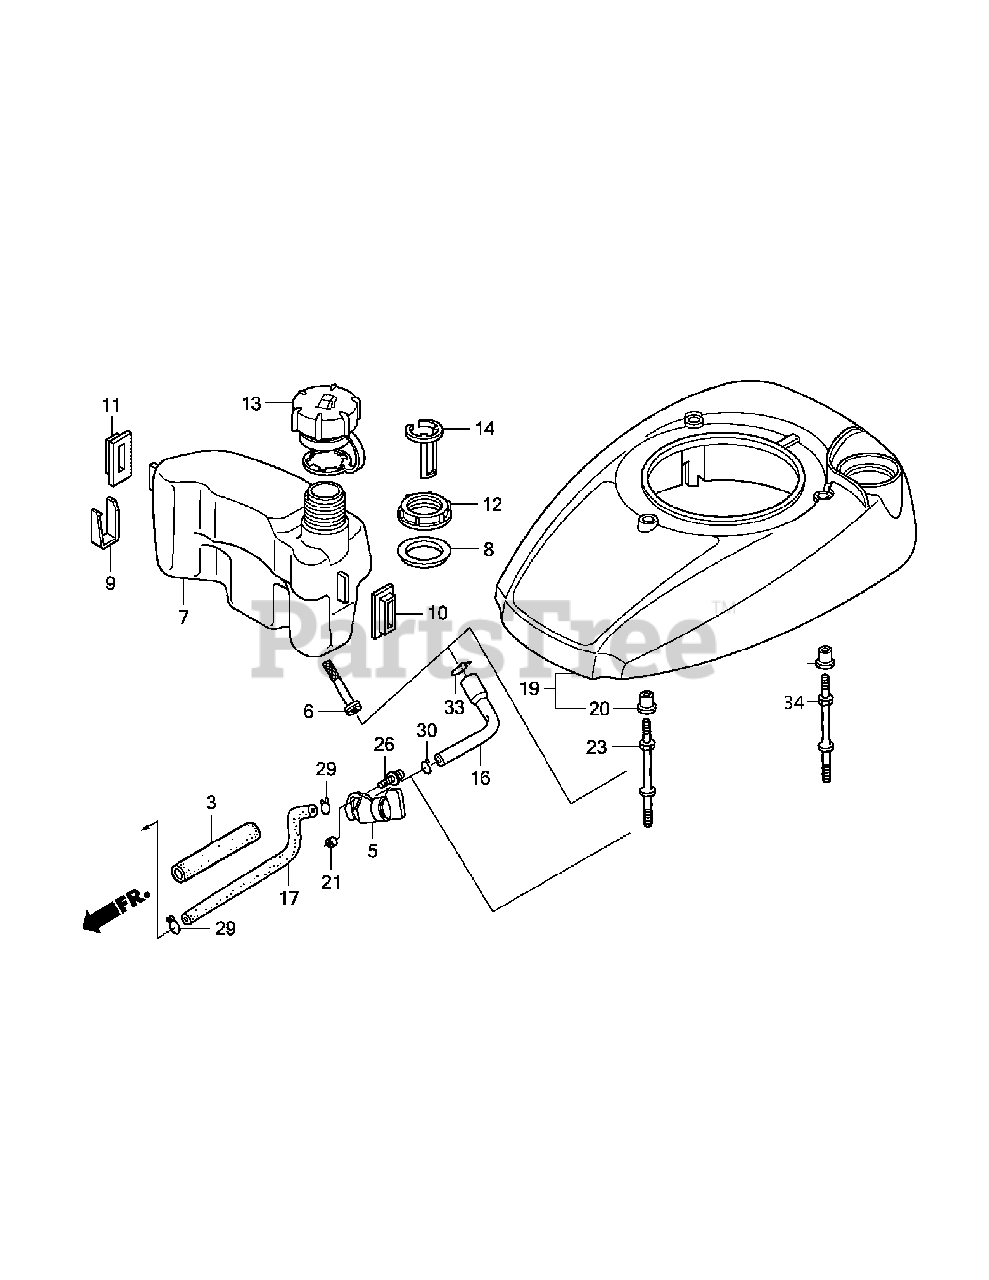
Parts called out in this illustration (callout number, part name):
3	Fuel Line Sleeve
5	Petcock Assembly
6	Fuel Filter (to 2240292)
6	Fuel Filter (from 2240293)
7	Fuel Tank
7	Fuel Tank Kit
8	Fuel Filler Neck Seal
9	Tank Mounting Clip
10	Tank Mounting Rubber
11	Tank Mounting Rubber
12	Tank Mounting Nut
13	Fuel Cap Assembly
14	Fuel Level Gauge
16	Fuel Tank Tube
17	Fuel Tube
19	Fan Cover, Black
20	Fan Cover Collar
21	Fuel Petcock Collar
23	Stud Bolt, 39.5mm
26	Screw w/ Washer, 5 x 10
29	Tube Clip, D8
30	Tube Clip, D10
33	Tube Clip, D12
34	Stud Bolt, 42.5mm
